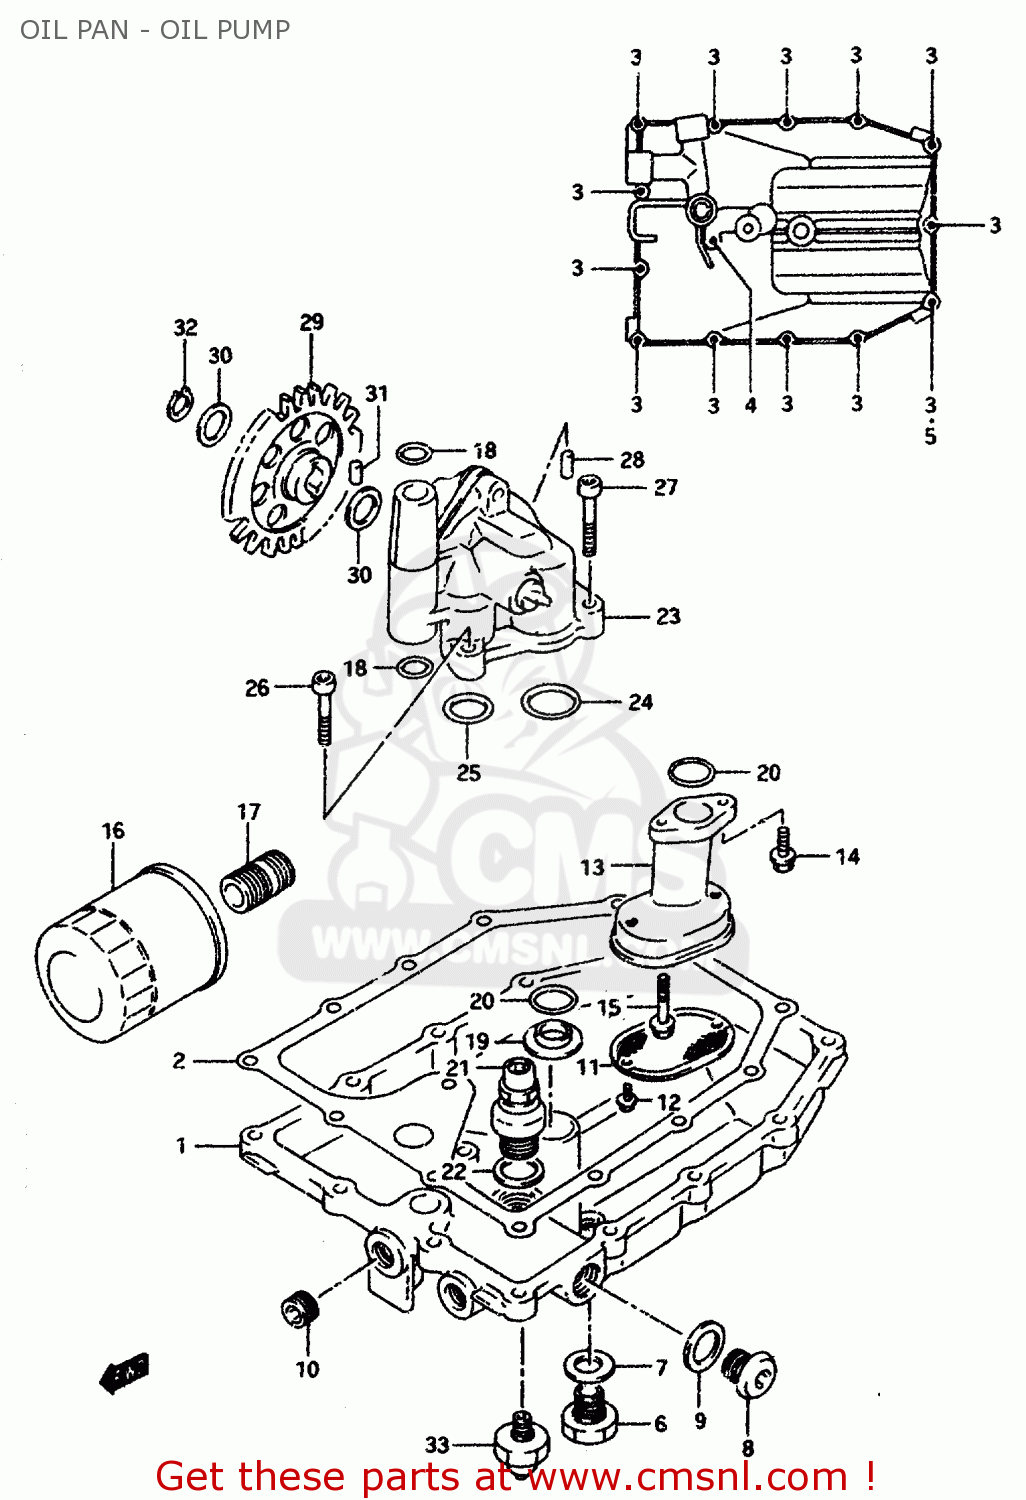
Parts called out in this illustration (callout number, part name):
1	PAN,OIL
2	GASKET,OIL PAN (NAS)
3	BOLT
4	BOLT
5	GASKET(5.8X11X1.2) (NAS)
6	PLUG
7	GASKET(13.8X18.8X4.8) (NAS)
8	PLUG
9	GASKET(16X22X2) (NAS)
10	JET,OIL PAN GALLERY
11	STRAINER,ENGINE OIL
12	BOLT
13	PROTECTOR,OIL STRAINER
14	BOLT
15	BOLT
16	FILTER ASSEMBLY,ENGINE OIL
17	UNION,OIL STAND
18	O RING(D:2.4,ID:11.8)
19	GASKET,OIL OUTLET (NAS)
20	O RING(D:3.2,ID:17.8)
21	VALVE ASSEMBLY,OIL RELIEF
22	GASKET(16X22X2) (NAS)
23	PUMP ASSY,ENGINE OIL
24	O RING(D:2.4,ID:26.2)
25	O RING(D:3.2,ID:17.8)
26	BOLT
27	BOLT
28	PIN
29	GEAR,OIL PUMP DRIVEN(NT:37)
30	SHIM
31	PIN(5X18)
32	CIRCLIP,12 MM
33	SWITCH ASSEMBLY,OIL PRESSURE
